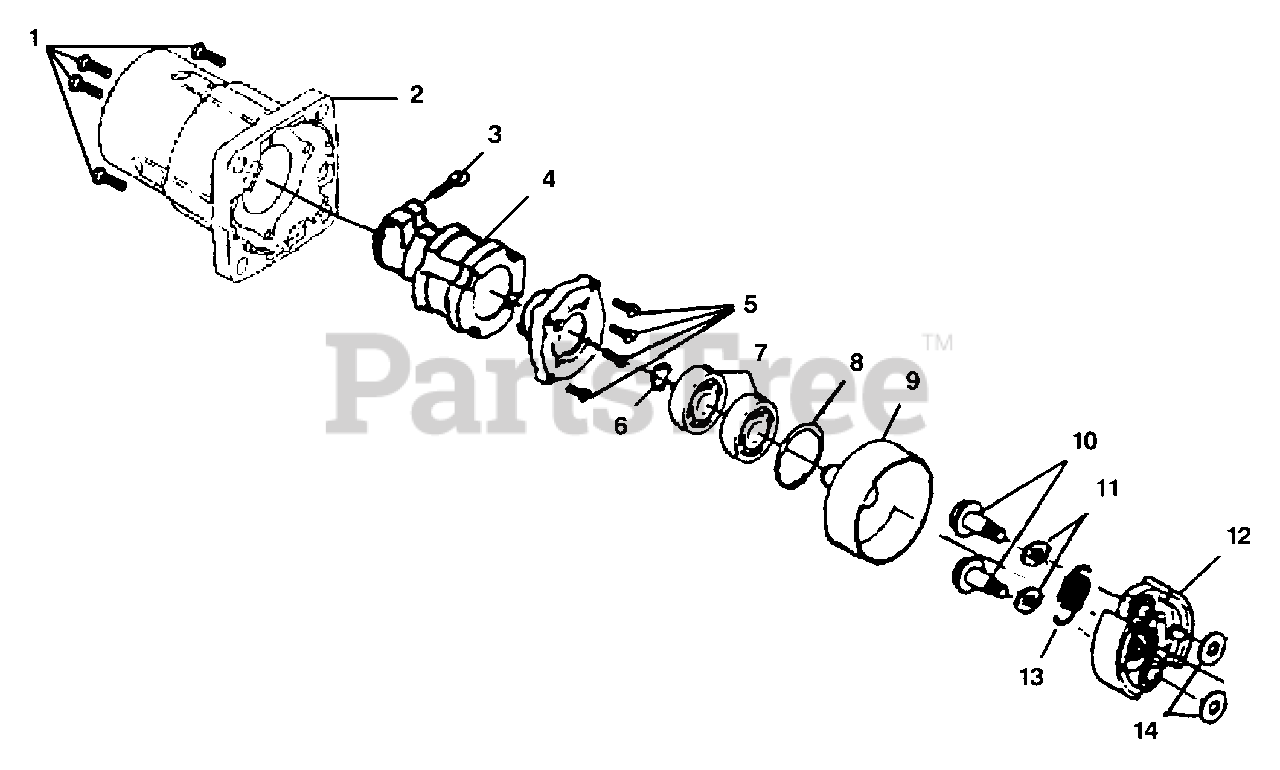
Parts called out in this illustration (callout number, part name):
1	BOLT & WASHER
2	CLUTCH CASE ASSY.
3	BOLT
4	INSERT RING
5	BOLT, ALLEN HEAD
6	SNAP RING
8	SNAP RING
9	CLUTCH DRUM
10	BOLT, CLUTCH
11	WASHER, CLUTCH BOLT
12	CLUTCH SHOE ASSY.
13	SPRING, CLUTCH
14	WASHER, CLUTCH
